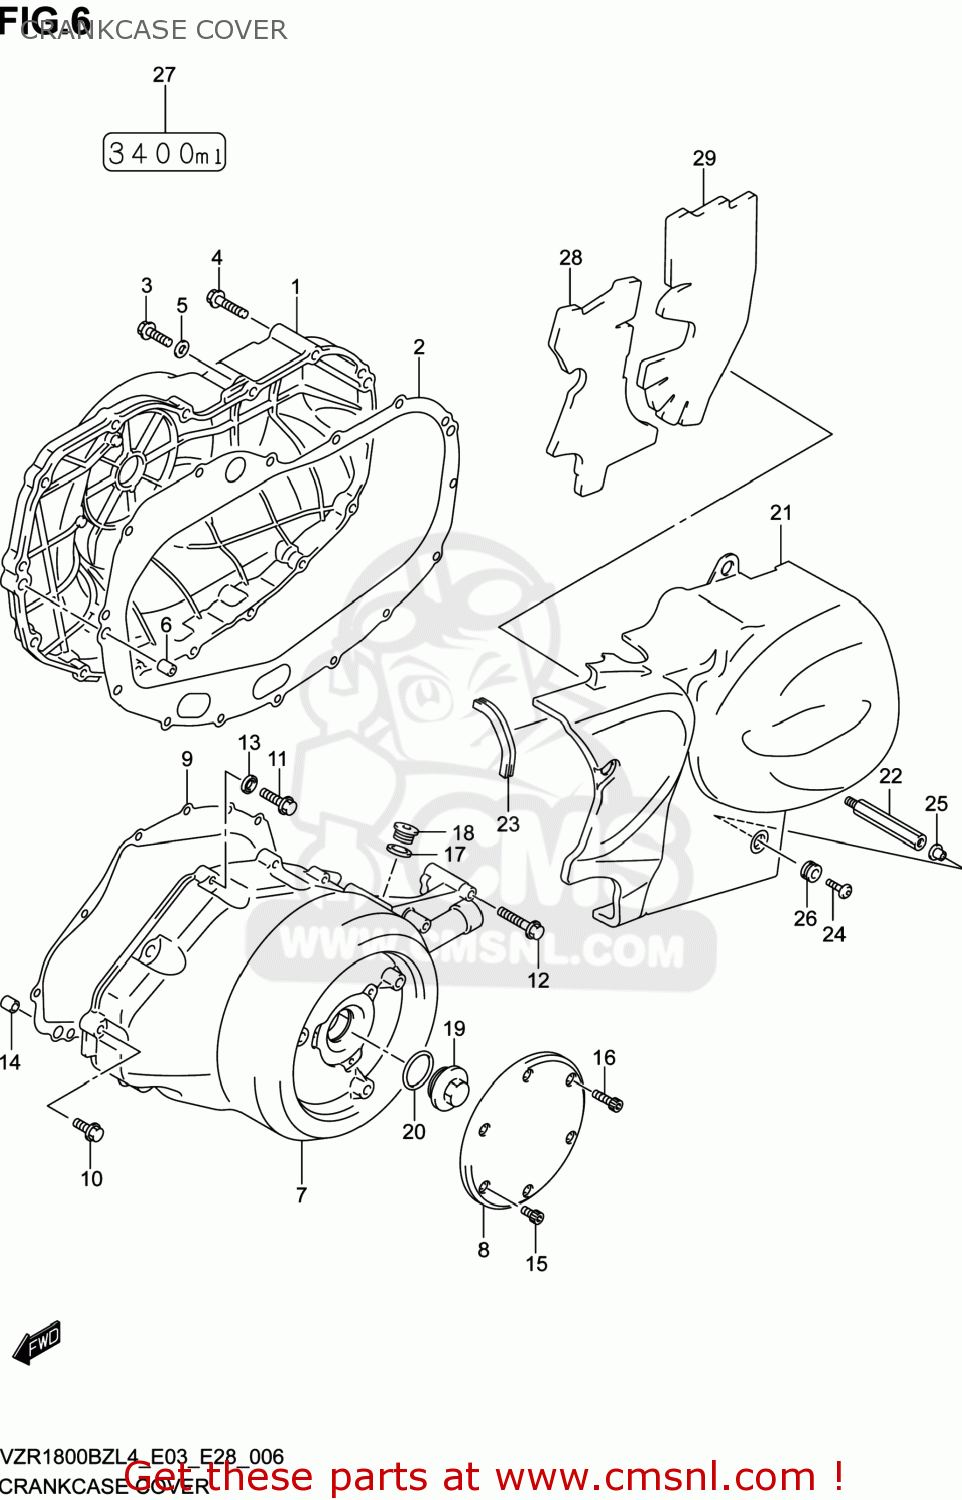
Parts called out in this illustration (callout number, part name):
1	COVER,CLUTCH
2	GASKET,CL COVER (NAS)
3	BOLT(6X30)
4	BOLT(6X60)
5	GASKET(5.8X13X1.2) (NAS)
6	PIN
7	COVER,MAGNETO
8	CAP,MAGNETO COVER
9	GASKET,MAGNETO COVER (NAS)
10	BOLT(6X30)
11	BOLT(6X50)
12	BOLT(6X70)
13	GASKET(5.8X13X1.2) (NAS)
14	PIN
15	BOLT(6X10)
16	BOLT(6X20)
17	GASKET(16X22X2) (NAS)
18	PLUG,16X8
19	CAP
20	O RING(D:3.1,ID:26.4)
21	COVER,SECONDARY DRIVE UNIT
22	BOLT,SEC DRIVE UNIT COVER
23	SCREW(6X20)
24	WASHER
25	CUSHION
26	NOTE,ENGINE OIL
27	DAMPER,MAGNETO COVER CAP
28	DAMPER,SEC DRIVE UNIT COVER
29	DAMPER,SEC DRIVE UNIT COVER
